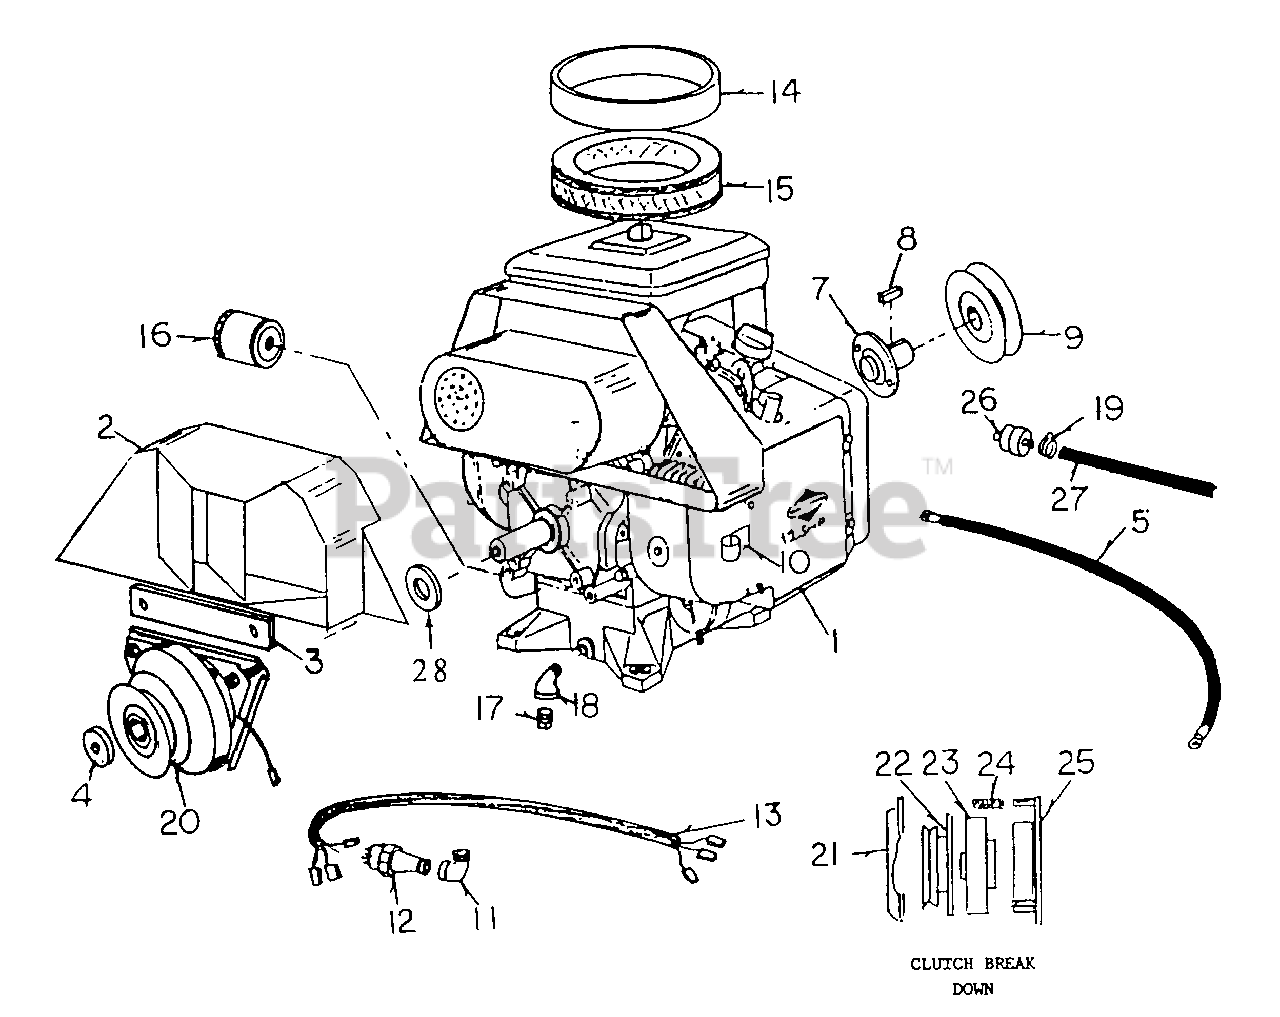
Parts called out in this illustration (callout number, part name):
1	Briggs & Stratton Twin
2	Air Duct
4	Clutch Retainer Washer
8	Key, 1/4" x 1/4" x 1"
10	Starter Cable Retainer
11	Street Elbow, 1/8" x 90°
12	Oil Sending Unit
13	Harness - oil unit
14	Precleaner
15	Air Cleaner Cartridge
16	Oil Filter
18	Street Elbow, 3/6"
19	Fuel Line Clamp
20	Clutch (Complete)
22	Clutch armature
23	Clutch Rotor
24	Spring & Nut Set (3 Ea.)
25	Clutch Coil
26	Fuel Filter
28	Spacer - clutch
